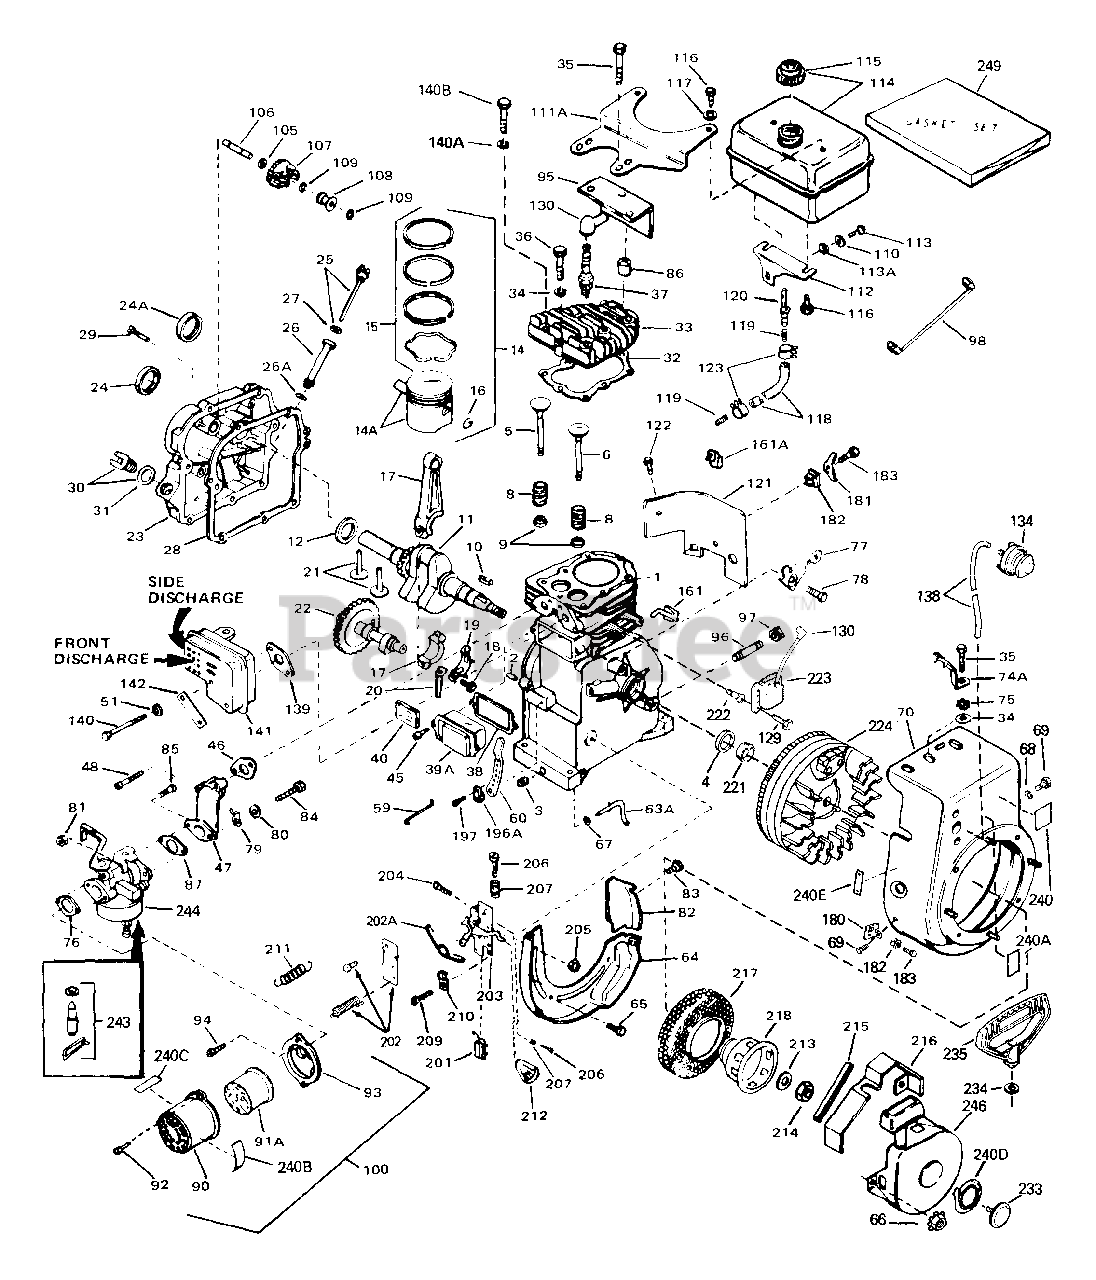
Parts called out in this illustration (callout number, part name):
1	"Cylinder Assy. (2-13/16" Bore)
2	Pin, Dowel
3	Plug, Pipe (Oil drain)
4	Seal, 0il
5	Valve, Intake (Std.)
5	Valve, Intake (1/32" oversize)
6	Valve, Exhaust (Std.)
6	Valve, Exhaust (1/32" oversize)
8	Spring, Valve
9	Cap, Lower valve spring
10	Key, Flywheel
11	Crankshaft
12	Washer, Thrust
14	Piston, Pin & Ring Assy. (Std.) (2-13 /16")
14	Piston, Pin & Ring Assy. (.010 oversi ze)
14	Piston, Pin & Ring Assy. (.020 oversi ze)
14A	Piston & Pin Assy. (Std.) (2-13/16")
14A	Piston & Pin Assy. (.010 oversize)
14A	Piston & Pin Assy. (.020 oversize)
15	Ring Set, Piston (Std.) (2-13/16")
15	Ring Set, Piston (.010 oversize)
15	Ring Set, Piston (.020 oversize)
16	Ring, Piston pin retaining
17	Rod Assy., Connecting
18	Screw, Connecting Rod
20	Dipper, 0fl
21	Lifter, Valve
22	Camshaft (Compression Release)
23	Cover, Cylinder
24	Seal, Oil
28	Gasket, Cylinder cover
29	Screw, Hex hd. Sems, 1/4-20 x 1
29	Screw, Hex hd. Sems, 1/4-20 x 1-1/4
30	Plug, Oil filler
31	Gasket, Oil fill plug
32	Gasket, Cylinder head
33	Head, Cylinder
34	Washer, Flat
35	Screw, Hex Flange hd., 5/16-18 x 2
35	Screw, Special hex hd., 5/16-18 x 1-1 /2
35	Screw, Special hex hd. tapped, 5/16-1 8 x 2
36	Screw, Hex flange hd., 5/16-18 x 1-1/ 2
37	Plug, Spark (Champion J-8 or equivale nt)
38	Gasket, Breather
39A	Breather Assy. Incl.
40	Element, Breather
45	Screw, fil. hd. Sems, 10-24 x 1/2
46	Gasket, intake (1/32" thick)
47	Pipe, Intake
48	Screw, Fil. hd. Sems, 1/4-20 x 1-19/3 2
51	Lockwasher
59	Link, Governor-to-throttle
60	Lever, Governor
63A	Rod, Governor
64	Baffle, Blower housing
65	Screw, Hex washer hd. Durlok, 1/4-20 x 5/8
66	Rivet, Pop
66	Nut & Lockwasher Assy., 1/4-28
67	Washer, Flat
68	Washer, Flat
69	Screw, Hex hd. Sems, 1/4-28 x 7/16
70	Housing, Blower (5.56 starter mtg. bo lt
77	Bracket, Holddown
78	Screw, Hex washer hd. self-tap Sems, 10-24 x
81	Nut & Lockwasher Assy., 1/4-28
82	Extension, Baffle
83	Screw, Hex washer hd. shakeproof,
84	Screw, Hex hd., 1/4-28 x 7/8
85	Screw, Fil. hd., 1/4-28 x 1-1/16
87	Gasket, Carburetor
94	Screw, Fil. hd. Sems, 10-32 x 1/2
95	Baffle, Heat
98	Wire, Ground (0ne female, one double male &
98	Wire, Ground (One female & one hook f itting)
100	Cleaner Assy., Air (Polyurethane)
105	Washer, Flat
106	Shaft, Mechanical governor
107	Gear Assy., Governor
108	Spool Governor
109	Ring, Retaining
111A	Bracket, Fuel tank (Upper)
112	Bracket, Fuel tank (Lower)
113	Screw, Hex hd. w/beHeville washer, 1/ 4-20 x
113A	Washer, Flat
114	Tank Assy., Fuel (Black Poly)
115	Cap, Fuel filler (Red Plastic) (Spurt
115	Cap, Fuel filler (White Plastic) (Std .)
116	Screw, Hex washer hd. thread cutting, 1/4-15
118	Line, Fuel (Braided 16")
118	Line, Fuel (Braided 32")
118	Line, Fuel (Braided 8.25")
119	Spring, Fuel line
121	Extension, Blower housing
122	Screw, Fil. hd. Sems, 10-24 x 1/2
123	Clamp, Fuel line
129	Screw, Hex hd Sems, 1/4-20 x 5/8
130	Cover, Spark plug
138	Line, Primer
139	Gasket, Muffler
140	Screw, Fil. hd. Sems, 1/4-20 x 112
140	Screw, Fil. hd. Sems, 1/4-20 x 2-1/2
141	Muffler (Front Discharge)
161A	Clip, Wire retaining
180	Bracket, Grommet mounting
182	Grommet, Plastic
183	Screw, Pan hd. taptite, 8-32 x 3/8
196A	Clamp, Governor lever
197	Screw, Hex washer hd., 8-32 x 5/16
201	Terminal Assy.
203	Control Assy., Speed
204	Screw, Hex washer hd. Self-Tap, 10-24 x 9/16
204	Screw, Fil. hd. Sems, 8-32 x 1/2
204	Screw, Fil. hd. Sems, 8-32 x 3/8
205	Nut & Lockwasher
206	Screw, Ffl. hd., 5-40 x 7/16
206	Screw, Hex hd., 10-32 x 1 (Drilled th ru)
207	Spring, Compression
211	Spring, Extension
212	Knob, Speed control
213	Washer, Belleville
214	Nut, Flywheel
215	Seal, Snow guard
216	Guard, Starter
217	Screen, Starter
218	Cup, Starter
240	Decal, Instruction
240A	Decal, Instruction
240C	Decal, "Choke"
240E	Decal, Control
243	Inlet Needle, Seat & Clip Assy.
244	Carburetor
246	Starter, Rewind
249	Gasket Set
